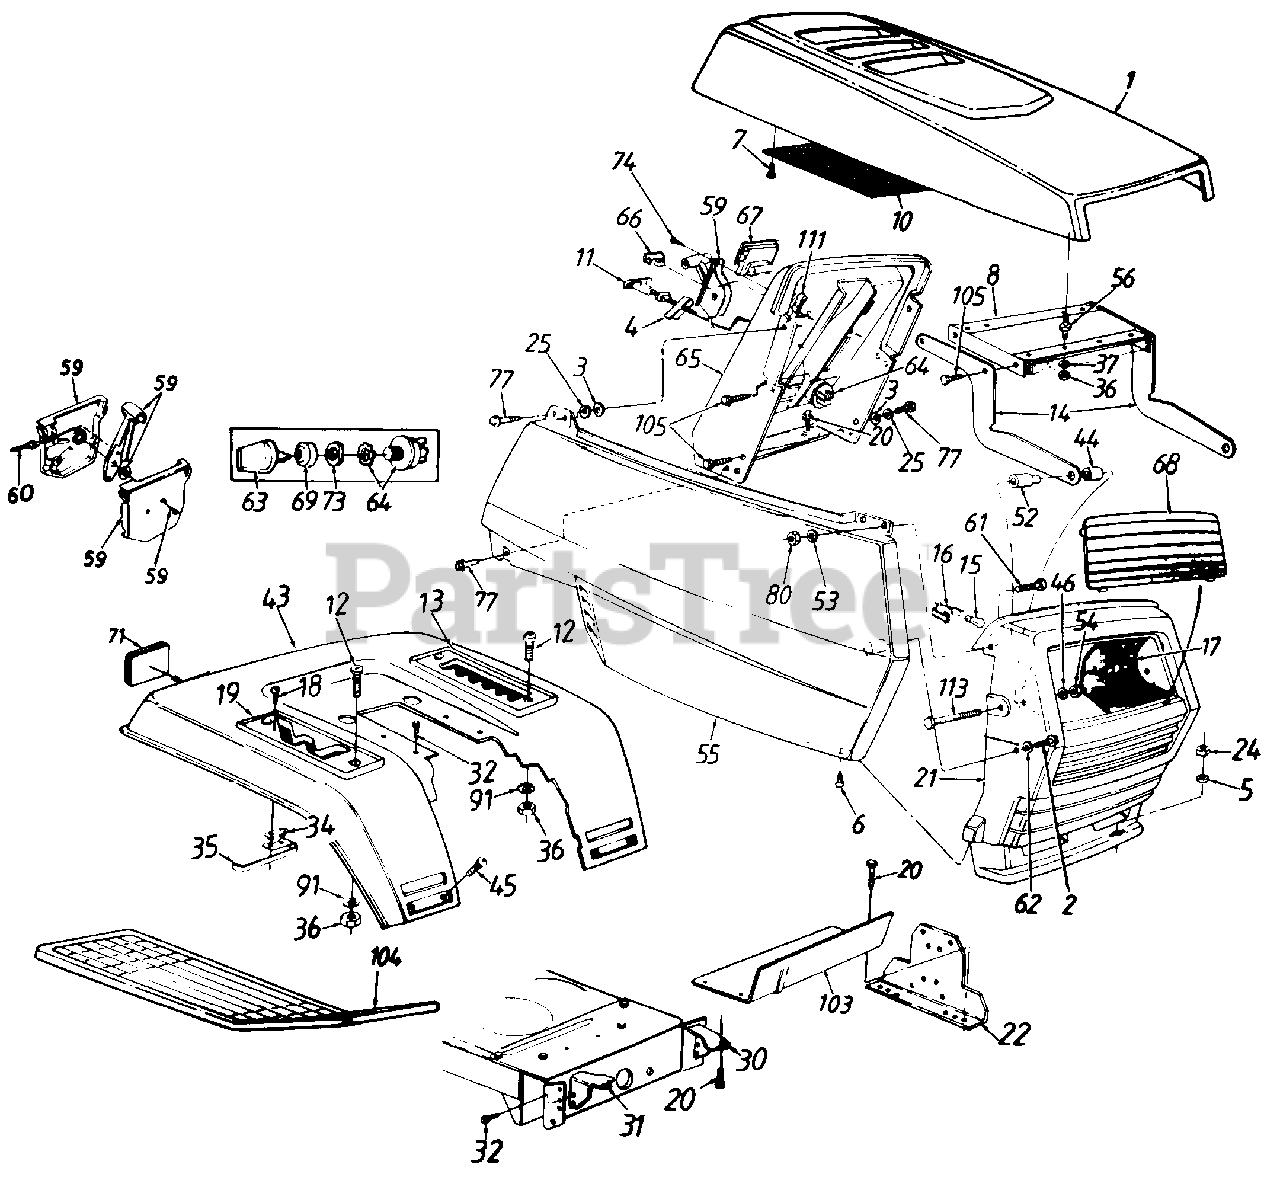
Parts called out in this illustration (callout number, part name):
3	Bolt Retainer 1/4" I.D.
4	Retainer Clip
5	Fl-Wash. .34" I.D. x .68"
6	Truss Mach. AB-Tap Scr. #10 x .5" Lg.
7	Hex Wash Hd. AB-Tap Scr. #8 x .5" Lg.
8	Hood Plate
11	Choke Control
12	Truss Mach. Scr. 1/4-20 x .75" Lg.
13	7-Speed Index Brkt.
14	Hood Hinge
15	Lamp
16	Twist Lock-Lamp Socket
17	Reflector-Headlight
18	Hex Wash. Hd. AB-Tap Scr. #8 x .5" Lg.
19	Forward/Reverse Index Brkt.
20	Hex Bolt 5/16-18 x .75" Lg.
21	Grille
24	Hex Nut 5/16-18 Thd.
25	Fl-Wash. 1/4" I.D. x .93n O.D.
30	Grille Mount Brk't.-L.H.
31	Grille Mount Brk't.-R.H.
32	Hex Wash. Hd. AB-Tap Scr. 5/16 x .75" Lg.
34	Insulator Nut Plate
35	Reverse Safety Switch
36	Hex Nut 1/4-20 Thd.
37	Bell-Wash. .265" I.D. x .75"
43	Rear Fender
44	Spacer .33" I.D. x .625" O.D.
45	Carriage Bolt 1/4-20 x .50" Lg.
46	Fl-Wash. .328" I.D. x .68" O.D.
52	Shld. Spacer .33" I.D.
53	Fl-Wash. .281" I.D. x .5" O.D.
54	Hex L-Nut 5/16-18 Thd.
55	Side Cover-R.H.
56	Double Ended Stud 1/4-20 Thd.
59	Throttle Control Box Ass'y.
60	Throttle Control Wire
61	Hex Bolt 1/4-20 x .62" Lg.
62	Fl-Wash. .281n l.D. x .73" O.D.
64	Ignition Switch
65	Dash Panel
66	Light Switch
67	Ammeter
68	Lens
69	Ignition Switch Cap
71	Reflector
73	Ignition Switch Nut
74	Truss Mach. AB-Tap Scr. #10 x .5" Lg.
77	Hex Wash. Hd. Tap Scr. 1/4 x .75" Lg.
80	Hex L-Nut 1/4-20 Thd.
91	L-Wash. 1/4" I.D.
103	Gasoline Tank Support
104	Foot Pad-L.H.
105	Hex Tap Scr. 1/4-20 x .5" Lg.
111	Speed Nut 1/4-20 Thd.
113	Hex Bolt 5/16-18 x 2.75"
